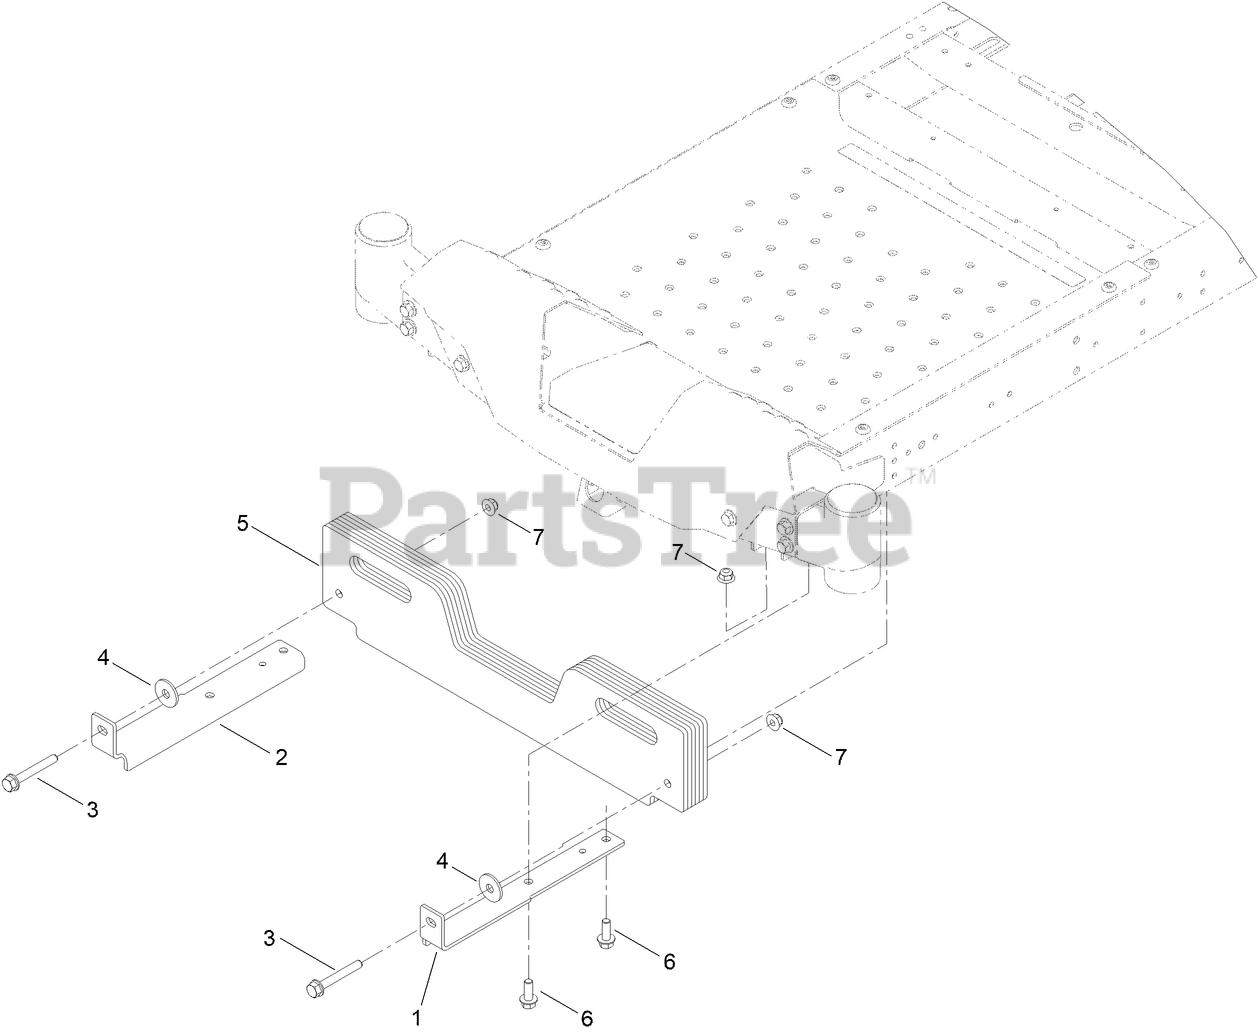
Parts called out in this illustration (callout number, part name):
1	BRACKET-WEIGHT, LH
2	BRACKET-WEIGHT, RH
3	SCREW-SPCL
4	WASHER
5	WEIGHT-BAGGER
6	SCREW-HHF
7	NUT-HF, NI
